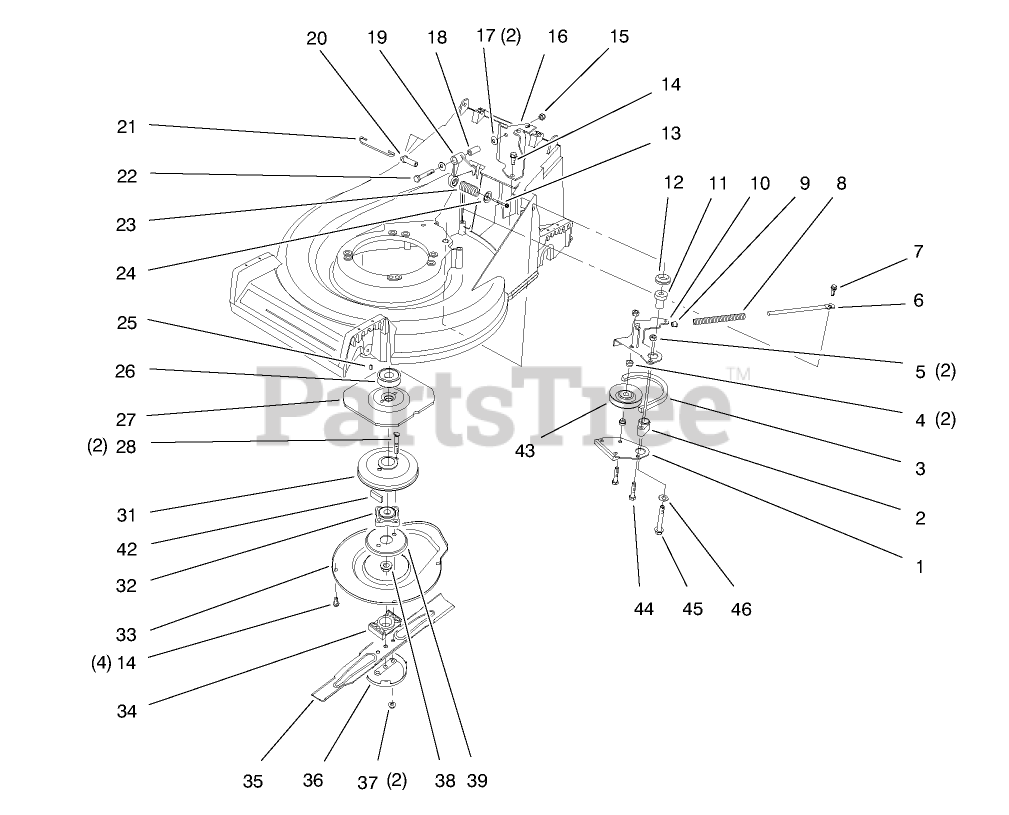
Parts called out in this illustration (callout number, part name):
1	BRAKE PLATE ASM
2	BRAKE PLATE HUB
3	V-BELT
4	IDLER PULLEY HUB
5	NUT-LOCK, NI
6	SPRING ROD
7	SCREW-SHOULDER
8	COMPRESSION SPRING
9	SPACER
11	BBC PM BUSHING
12	V-RING SEAL
13	SCREW-HWHTF
14	SCREW-HWHTF
17	WASHER-PLAIN
18	STRAIGHT BUSHING
19	CRANK
20	SPRING PIN
21	CONTROL LINK
22	SCREW-HH
23	COMPRESSION SPRING
24	RETAINER-SPRING
25	KEY-WOODRUFF
26	PULLEY
28	BOLT-BLADE
32	HUB ASM
36	CUP-SCALP, ANTI
37	NUT-LOCK
38	NUT-LOCK, NI
42	DAMPENER-VIBRATION
44	SCREW-HH
45	3/8-16 X 2-3/4 CAPSCR
